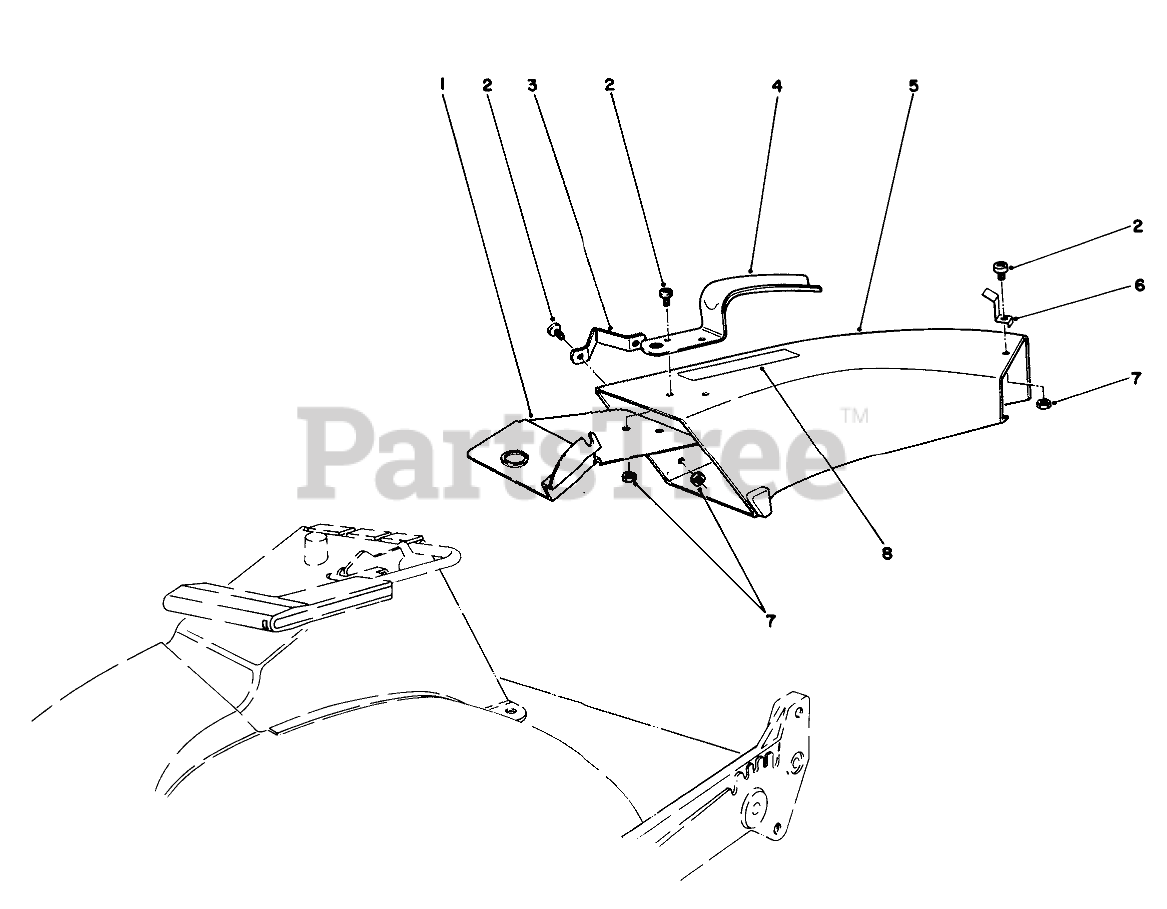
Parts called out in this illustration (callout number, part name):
1	Plate-Discharge Chut
2	10-24 X 5/8 PAN HD MS
3	SIDE BRACKET
4	CHUTE HANDLE
5	Chute-Discharge
7	NUT-LOCK, NI
8	DECAL CAUTION
